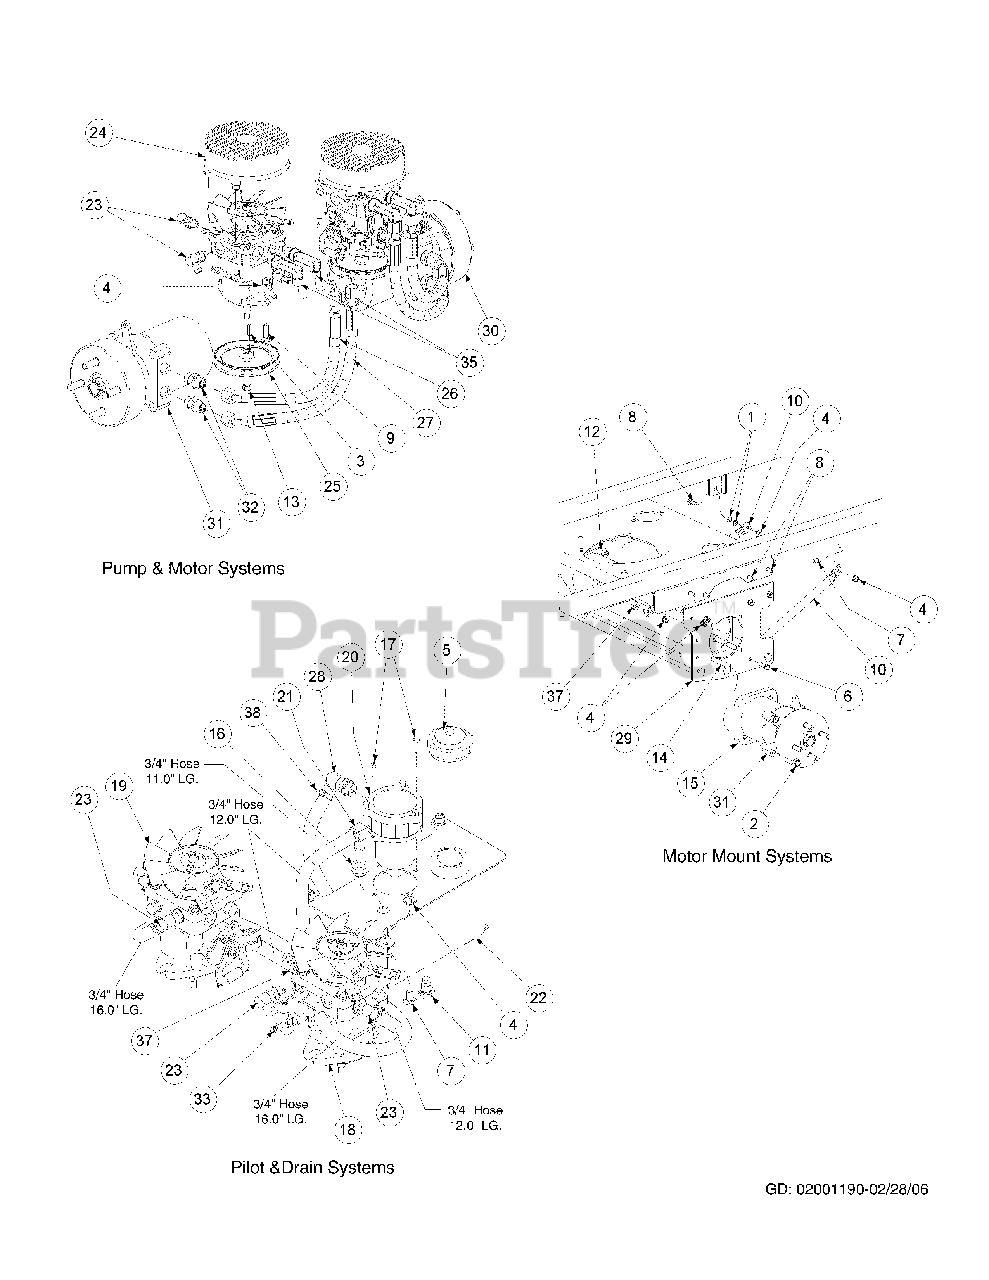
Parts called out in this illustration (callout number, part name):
1	Washer lock 3/8 zinc
2	Washer lock 3/8 zinc
3	Key, 3/16" x 7/8"
4	Flange Lock Hex Nut, 3/8-16
5	Cap, Hydro Oil Tank
6	Hex Cap Screw, 3/8 -16 x 1.25
7	Carriage Bolt, 3/8-16 x .75 LG.
8	Carriage Bolt, 3/8-16 x 1
9	Carriage Screw, 3/8-16 x 1.25
11	Oil Pan Drain Plug w/ Seal
12	Hydro Wheel Motor Backup Plate
13	Hex Nut, 3/8-24
14	Socket Head Capscrew, 1/2-13; 3-1/2
15	Hydro Motor Spacer
16	Grommet Fitting, .54 ID x .78 OD
17	Socket Low Head Cap Screw, 1/4-20 x 0.75
18	Hydro Pump, BDP-12, RH
19	Hydro Pump, BDP-12, LH
20	Hydraulic In-Tank Filter Includes:
21	Fitting Elbow Spur, 5/8 x 1/2
22	Hydraulic Tank Assembly
23	Fitting Elbow, 9/16 x 1/2
24	Fan Pump Shroud
25	Hydro Pump Pulley
26	Short Pressure Hose Assembly
27	Long Pressure Hose Assembly
28	Fitting Elbow, 3/4 x 1/2
29	Hydro Motor Frame Assembly
30	Hydro Motor, Left Hand Assembly w/ Brake & Drum
31	Hydro Motor, Right Hand Assembly w/ Brake & Drum
32	Adaptor Fitting, 8 x 10
33	Hose Clamp
34	Fuel Hose, .50 ID x .75 OD (79 in inches)
35	Adaptor, 8 x 8
36	Spacer .406 ID x 1.0 OD
37	Tee Fitting, 1/2
38	Hose Clamp, 1/2
